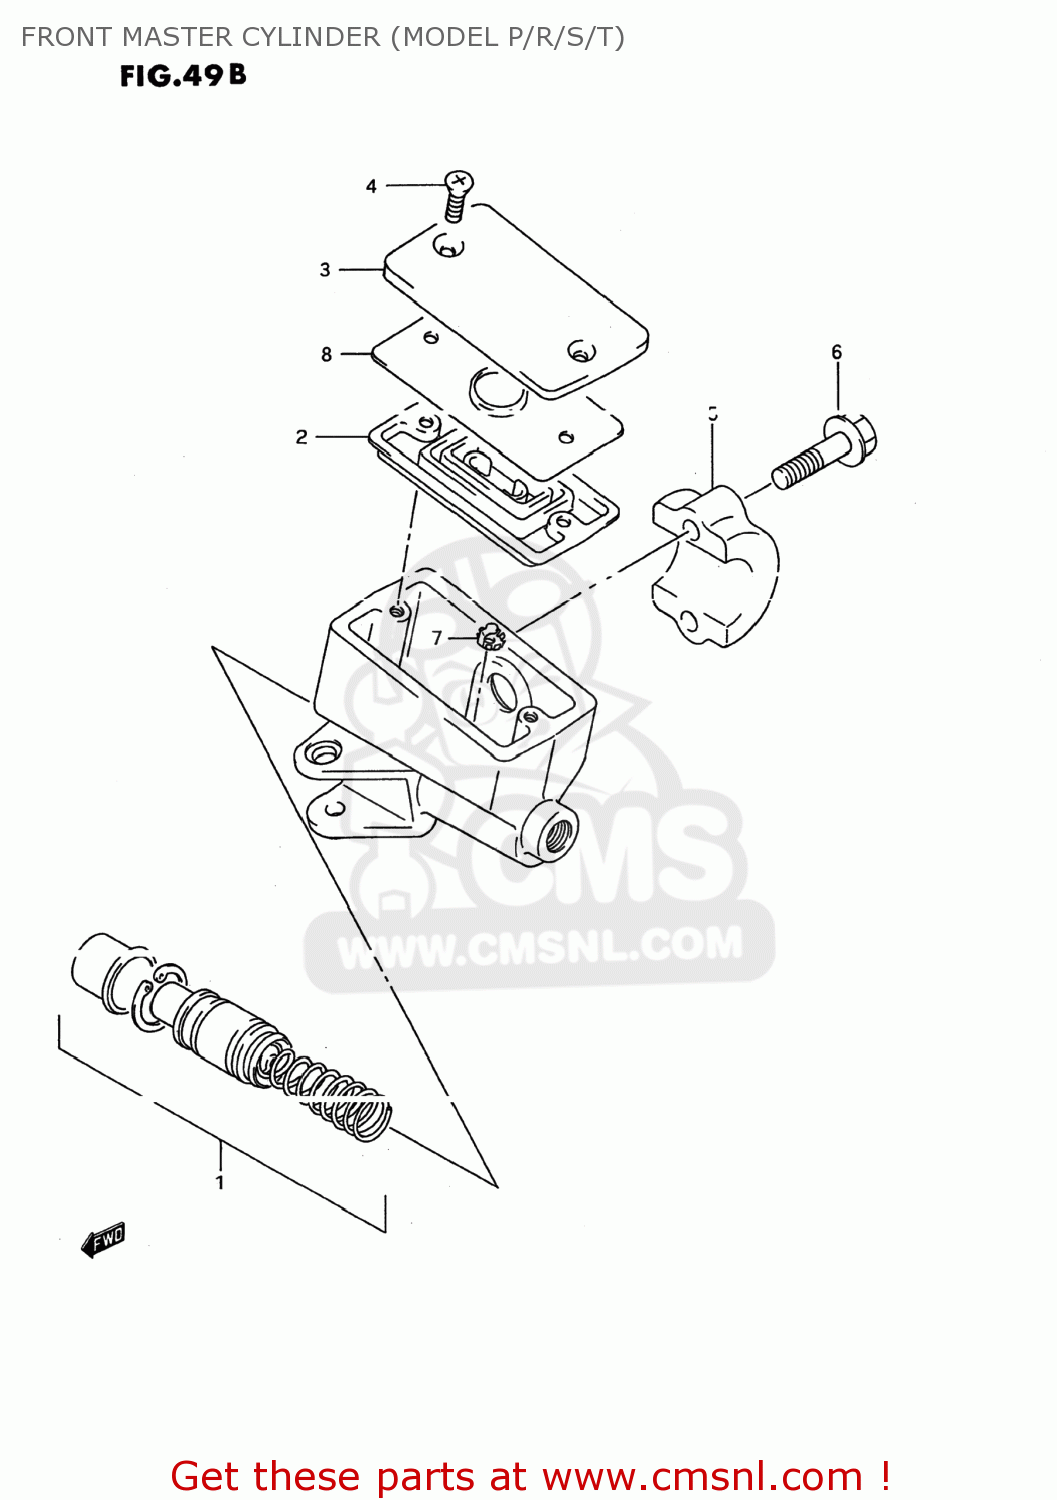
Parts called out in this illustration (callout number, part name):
1	PISTON & CUP SET
2	3
3	CAP
4	SCREW
5	HOLDER
6	BOLT(6X25)
7	PROTECTOR
8	PLATE,DIAPHRAGM
